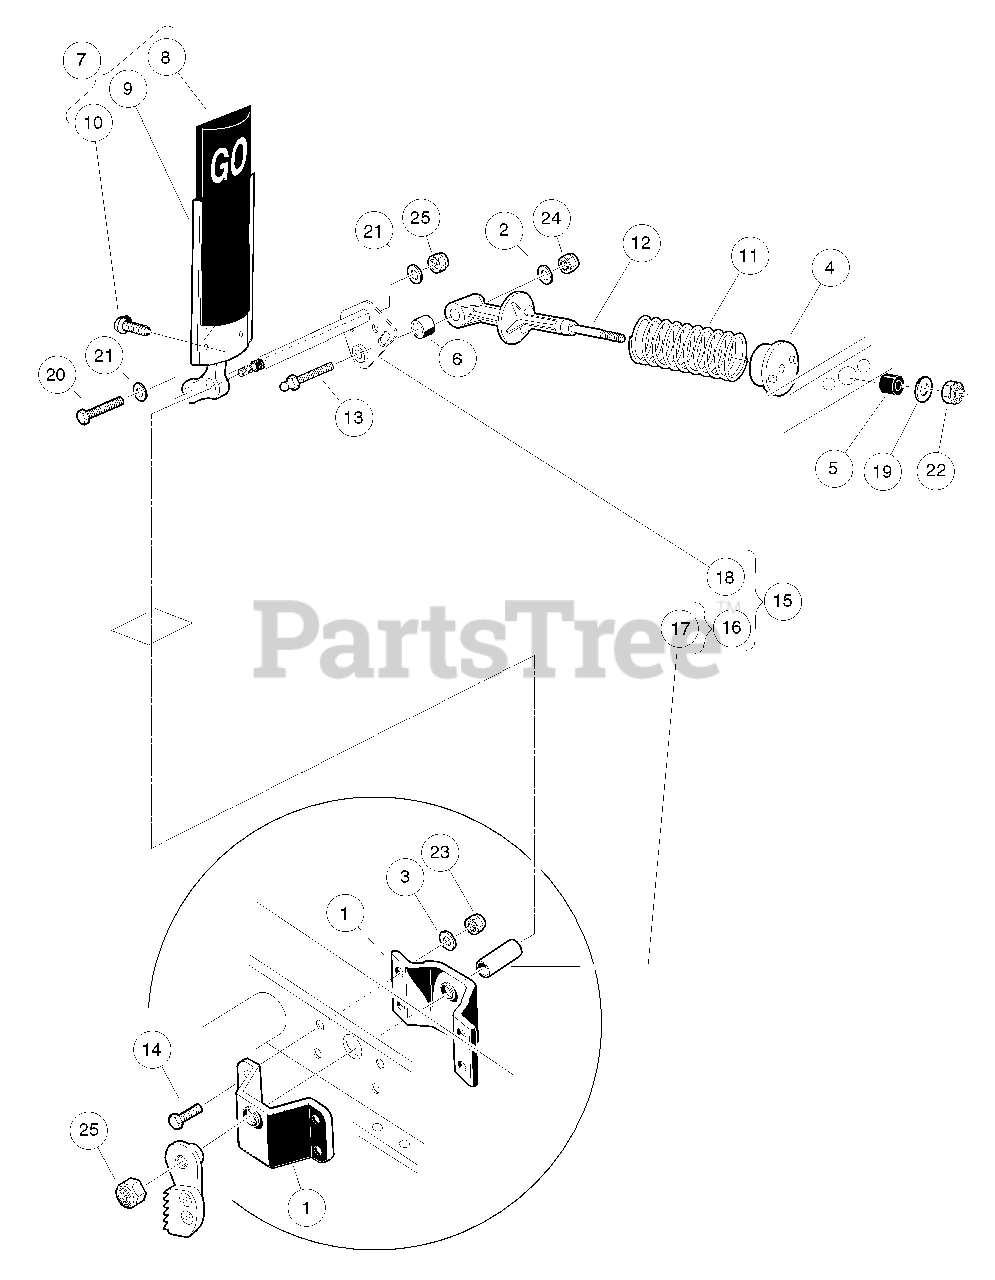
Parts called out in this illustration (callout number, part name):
1	Accelerator Bracket and Bearing Assembly
2	Washer, 1/4 Flat
3	Washer, 1/4 Flat
4	Cup, Spring
5	Bumper, Spring Return
6	Bearing, Pivot Support
7	Sub Asm, Accelerator Pedal
8	Pad, Accelerator Pedal
9	Accelerator Pedal Weldment
10	Screw, #10-16 Type AB, Sheet Metal
11	Spring, Accelerator Return
12	Retainer, Spring
13	Stud, 1/4-28 X 1.35 Ball
14	Screw, 1/4-20 X 1.125 Hex Cap
15	Kit, Accelerator Pivot Rod Assembly
16	Spacer Assembly
17	Spacer, Accelerator
18	Pivot Rod Weldment
19	Washer, 5/16 Type A Flat
20	Screw, 3/8-16 X 1.50 Hex-Head Cap
21	Washer, 3/8 Type A Flat
22	Locknut, 5/16-18 Nylon Insert
23	Locknut, 1/4-20 Nylon Insert
24	Locknut, 1/4-28 Nylon Insert
25	Locknut, 3/8-16 Hex
